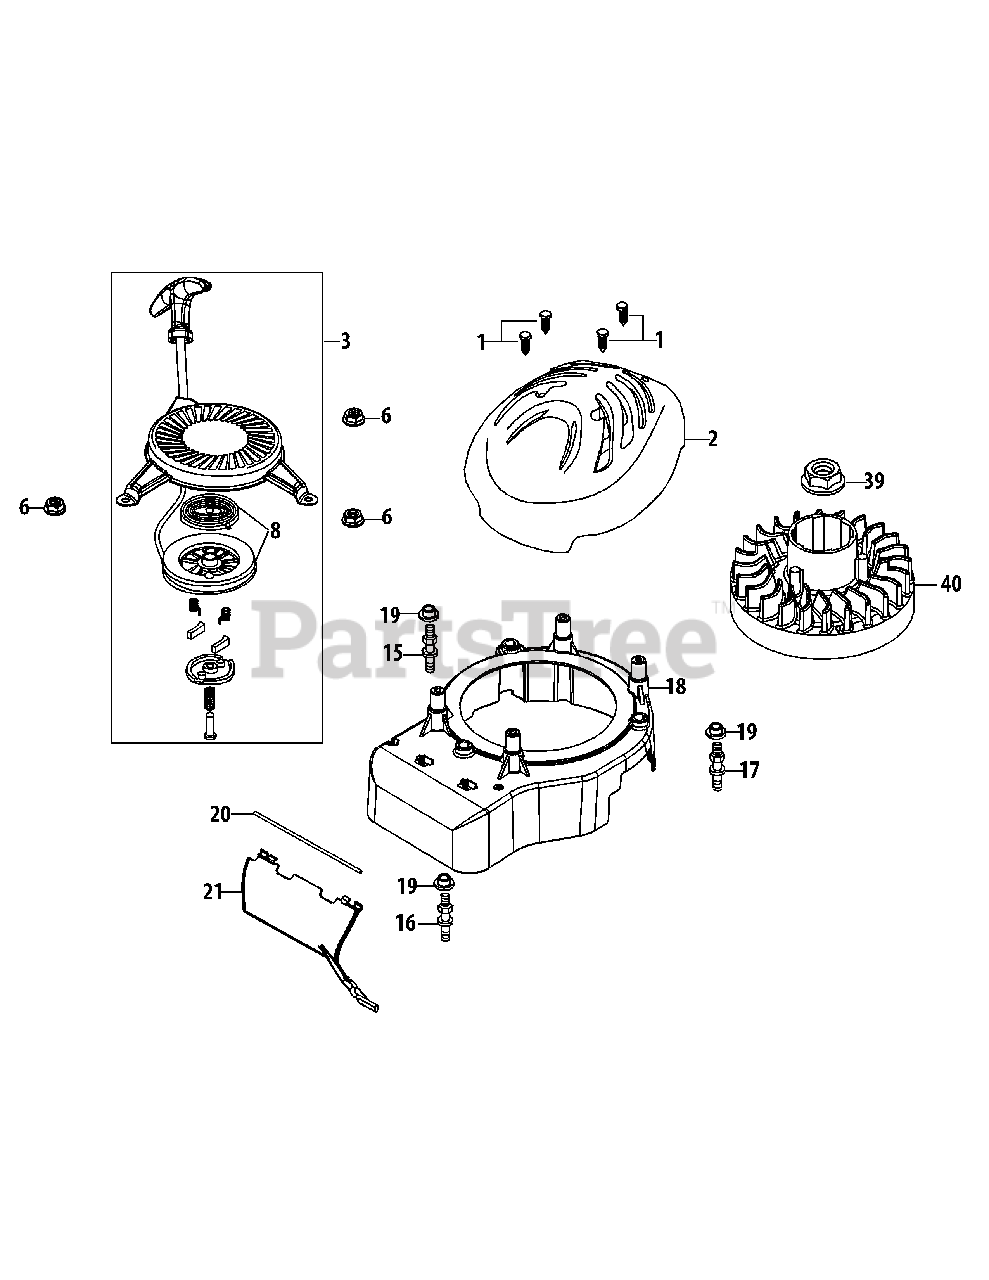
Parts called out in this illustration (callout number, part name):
1	Screw, Hilo #12-16 X 1.00"
2	Outer Shroud (Application Specific)
3	Recoil Starter Assembly
6	Nut M6X10Mm
8	Recoil Spring & Pulley Assy
15	Stud Left/Black/Wh Zinc
16	Stud Front/Unmarked/Wh Zinc
17	Stud Right/White/Wh Zinc
18	Inner Shroud
18	Inner Shroud Assy (Incl.19)
19	Engine Shroud Spacer
20	Air Vane Shaft
39	Flywheel Nut M14
